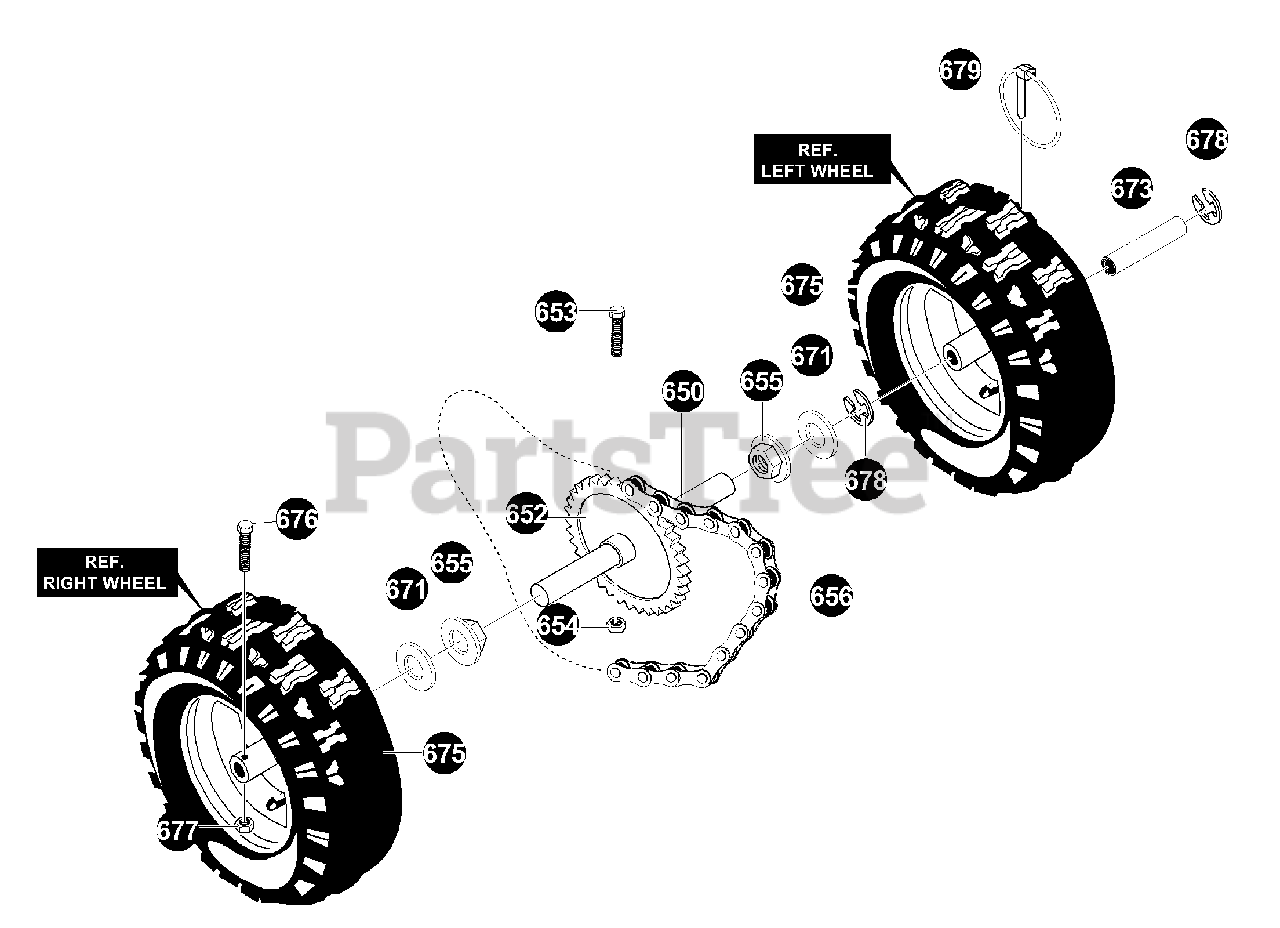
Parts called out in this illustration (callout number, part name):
650	SHAFT, AXLE
652	SPROCKET, HUB
653	SCREW 1/4-20X2.25
654	NUT, 1/4-20 REGHEXCTRLK
655	BEARING, FLANGE
656	CHAIN, ROLLER #42 X 41P
671	FLATWASHER .765X1.12X.06
673	BUSHING, WHEEL 4"LG
675	TIRE & RIM 16X4.8X4
676	SCREW, SHR 1/4-20X1.75
677	NUT 1/4-20 REGHEXCTRLK
678	RING, RETAINING
